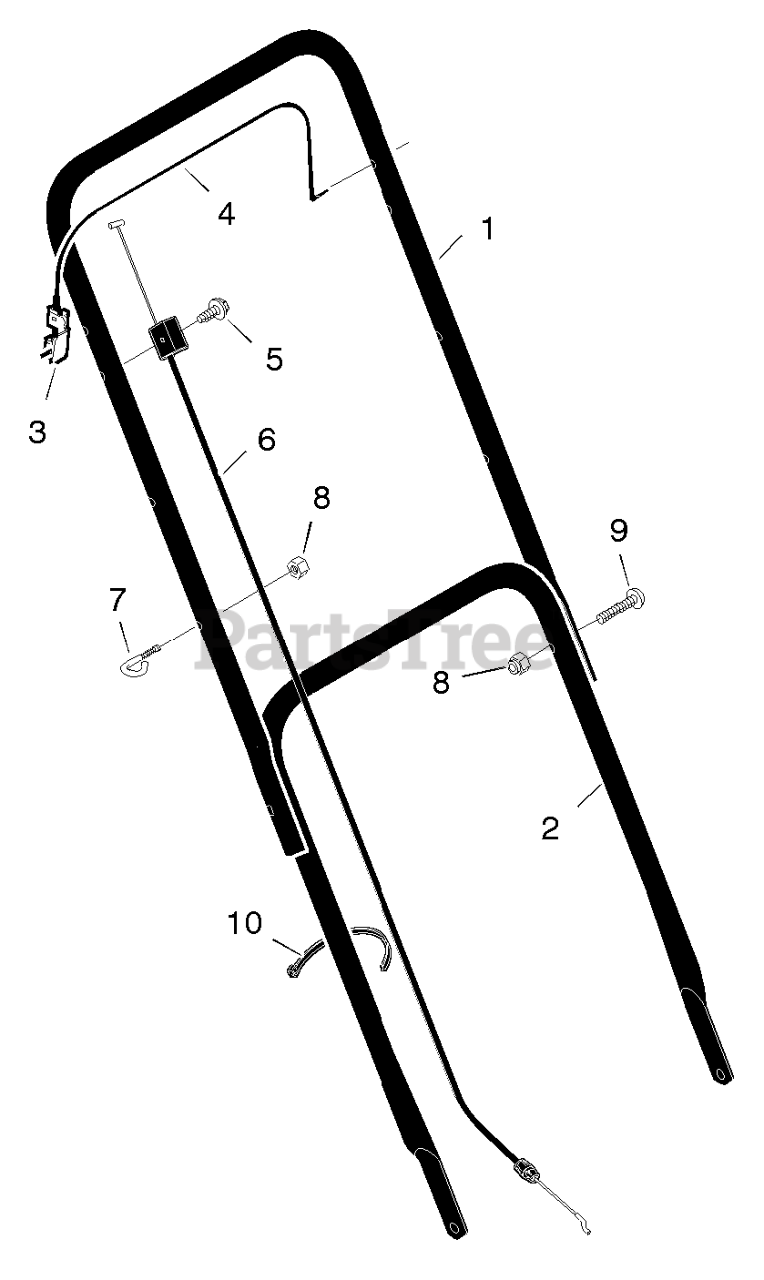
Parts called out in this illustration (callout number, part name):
1	Handle, Upper (Black)
2	Handle, Lower (Black)
3	Bracket, Stop Lever
4	Lever, Stop
6	Engine Stop Cable
7	GUIDE, ROPE
8	Locknut
10	Fastener, Cable
